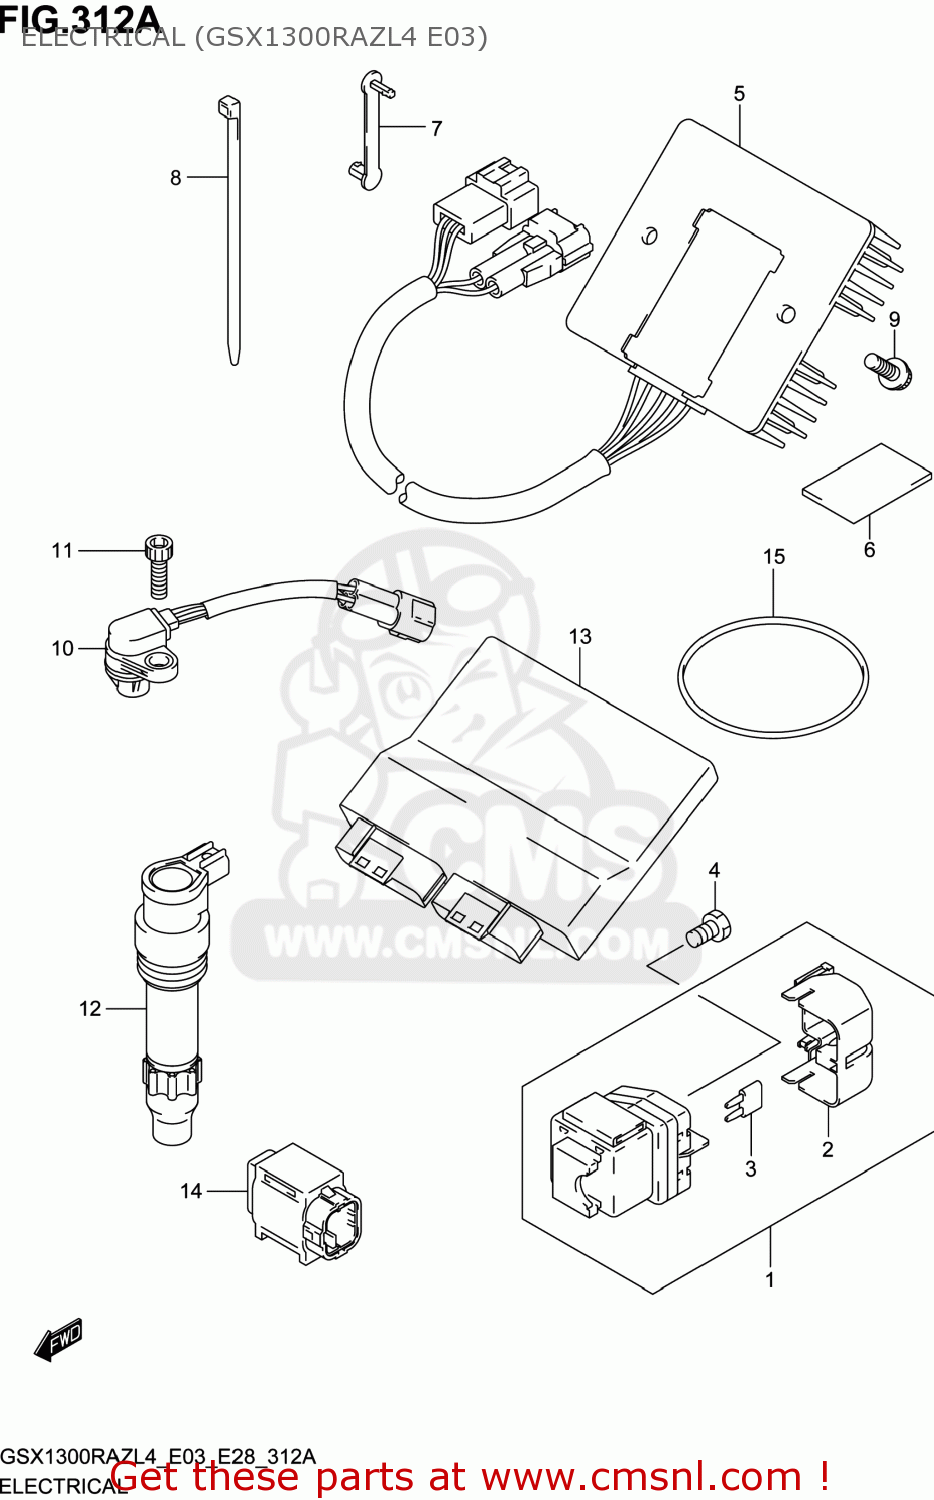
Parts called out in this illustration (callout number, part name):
1	RELAY ASSY,STARTING MOTOR
2	COVER
3	FUSE(30A)
4	SCREW(6X8)
5	RECTIFIER ASSY
6	CUSHION(30X50X3)
7	CLAMP(L:63)
8	CLAMP(L:145)
9	SCREW
10	SENSOR ASSY,CAM POSITION
11	BOLT
12	COIL ASSY,IGNITION
13	CONTROL UNIT,FI
14	SENSOR ASSY,FUEL CUT
15	O RING(D:3.5,ID:76)
